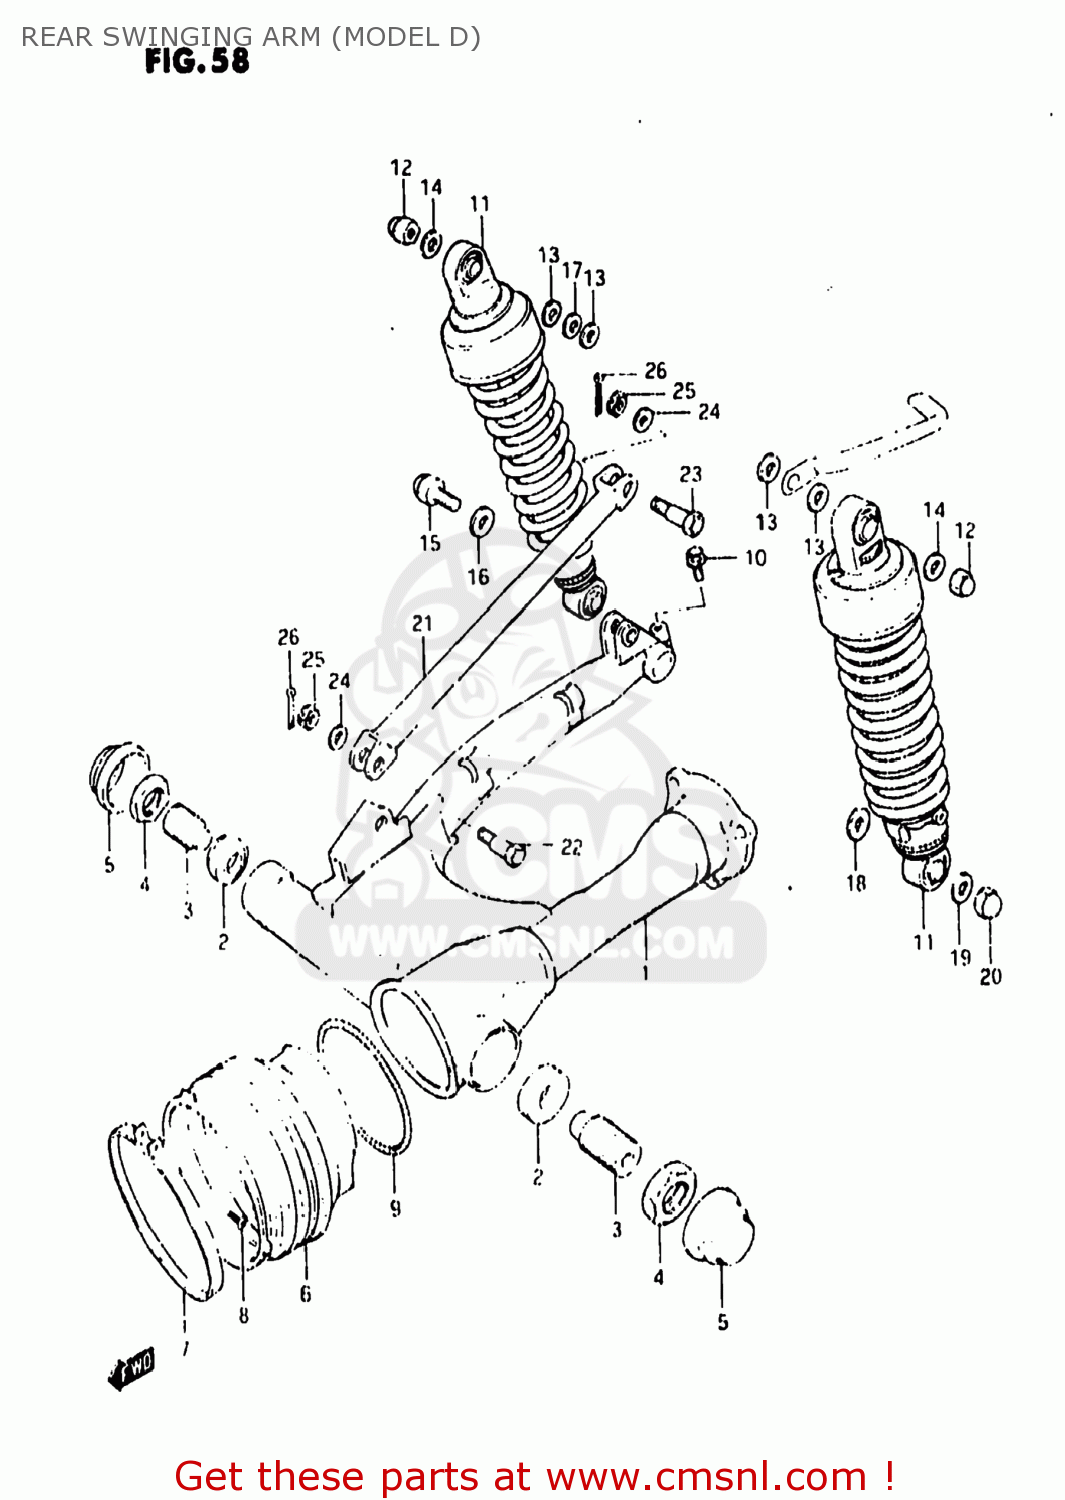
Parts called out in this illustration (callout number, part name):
1	SWING ARM SET,REAR (B
2	BEARING(17X40X13.25)
3	BOLT,REAR SWING ARM PIVOT
4	NUT
5	CAP,REAR SWING ARM PIVOT
6	BOOT,PROPELLER SHAFT
7	CLAMP
8	SCREW 4X25
9	SPRING,PROPELLER SHAFT
10	BOLT
11	ABSORBER ASSEMBLY,REAR SHOCK
12	NUT
13	WASHER
14	WASHER
15	BOLT 12X33
16	WASHER (12.5X24X1.6)
17	WASHER (12.5X24X3.2)
18	WASHER
19	WASHER
20	NUT
21	TORQUE LINK,REAR
22	BOLT
23	BOLT(10X39)
24	WASHER
25	NUT
26	PIN 20X20
